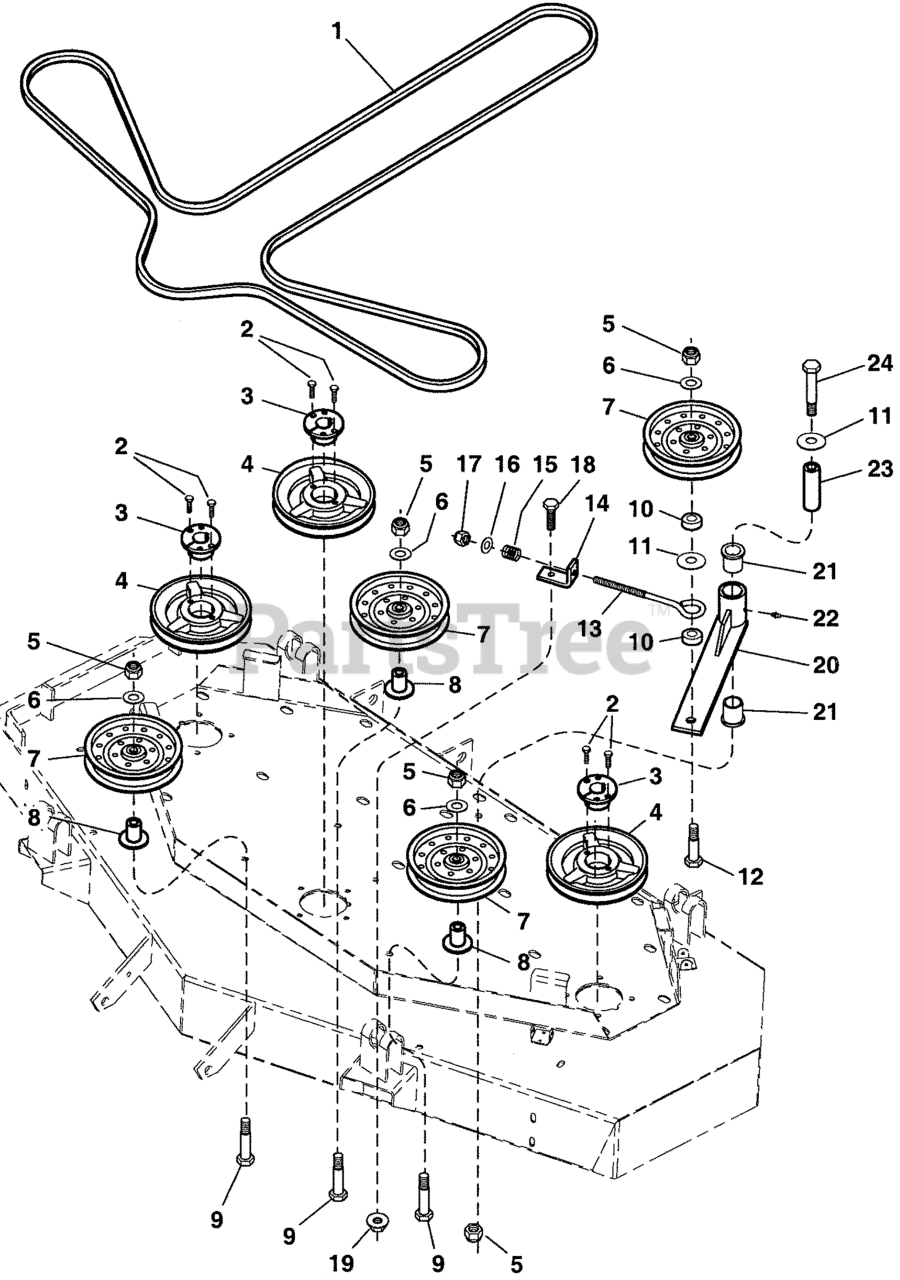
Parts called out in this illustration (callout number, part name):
1	BELT, 61" Deck
2	BOLT, 1/4-20 X 1" GD5 CZ
3	HUB, Taper Lock
4	PULLEY, Spindle
5	NUT, 1/2-13 HEX NYLON LOCK
6	WASHER, 1/2 SAE
8	IDLER PULLEY MOUNT - RED
9	BOLT, 1/2-13 X 3-1/2, HEX HD, GD5, CZ (SV)
10	IDLER SPACER
11	WASHER, USS, 1/2
12	BOLT, 1/2-13 X 3" GD5 CZ
13	EYEBOLT
14	SPRING ANCHOR
15	SPRING, Compression
16	WASHER, 3/8 SAE
17	NUT, 3/8-16 HEX NYLON LOCK
18	BOLT, 3/8-16 X 1" GD5 CZ
19	NUT, Hex, Serrated Flange, 3/8-16
20	IDLER ARM - RED
21	BUSHING, FLANGE
22	GREASE FITTING
23	IDLER ARM PIVOT SHAFT
24	BOLT, 1/2-13 x 4-1/2
